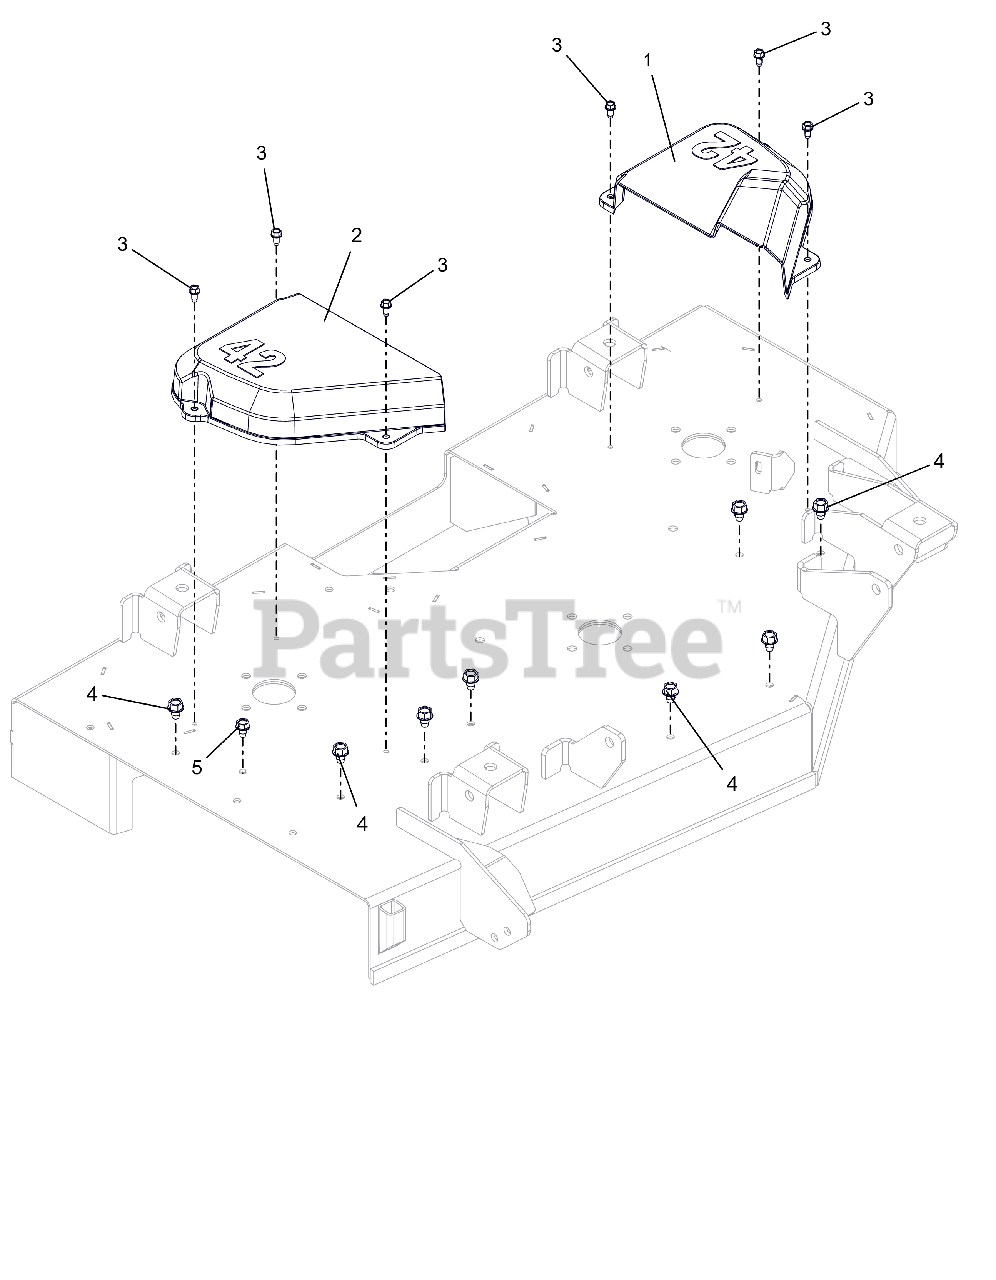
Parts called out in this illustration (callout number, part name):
1	COVER, BELT 42" LH
2	COVER, BELT 42" RH
3	SCR-TAP .25-20X.50 HWH ZCC
4	SCR,TAP .375-16X.50 HWH TR ZCC
5	SCR,TAP .312-18X.50 HWH TR ZCC
